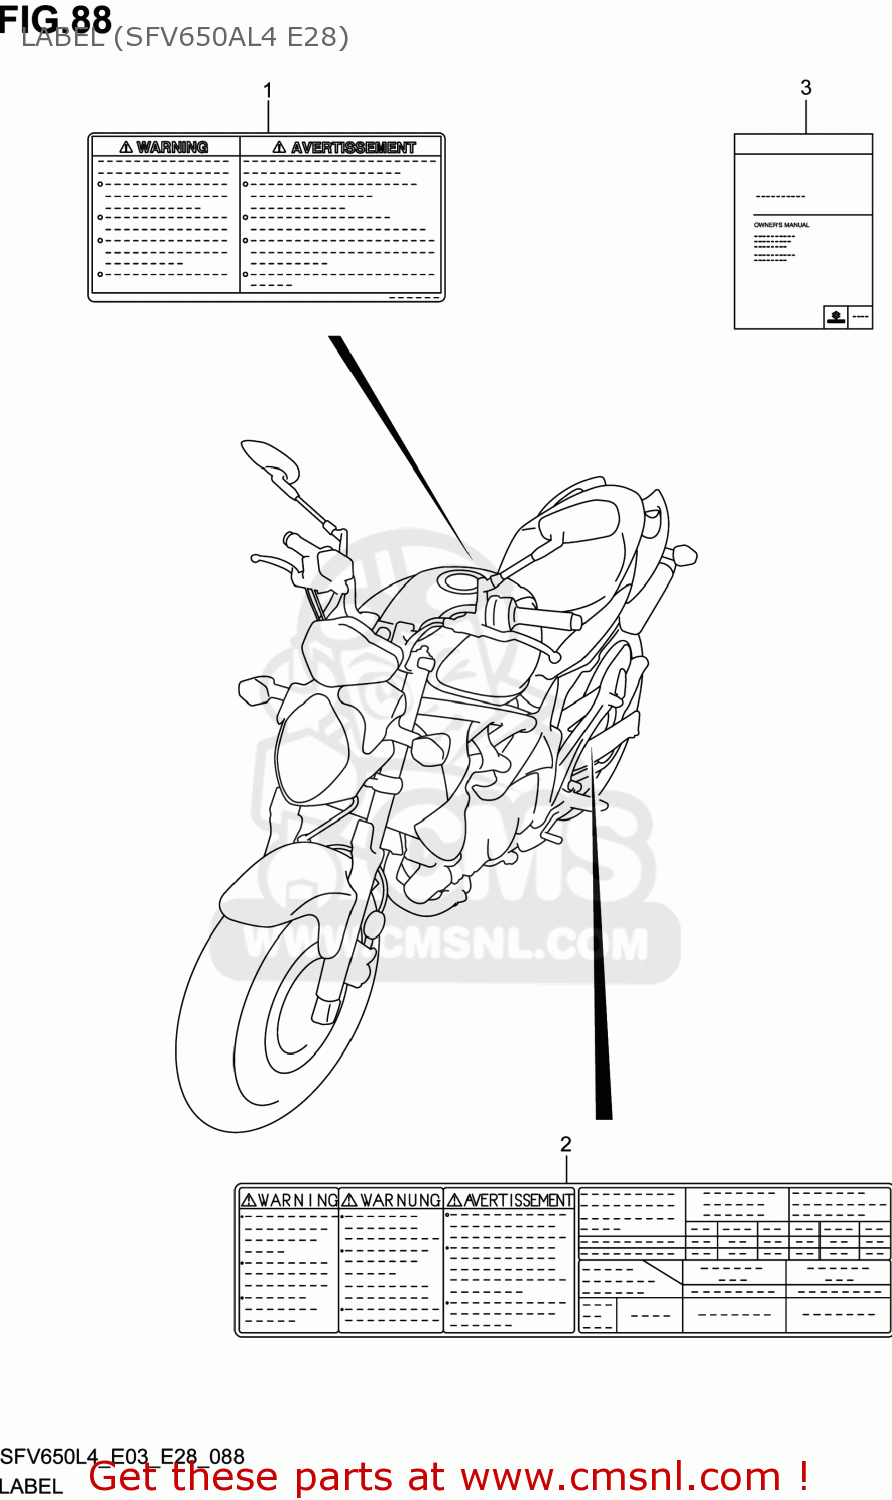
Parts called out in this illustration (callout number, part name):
1	LABEL,GENERAL WARNING
2	LABEL,TIRE INFORMATION
3	MANUAL,OWNER'S
